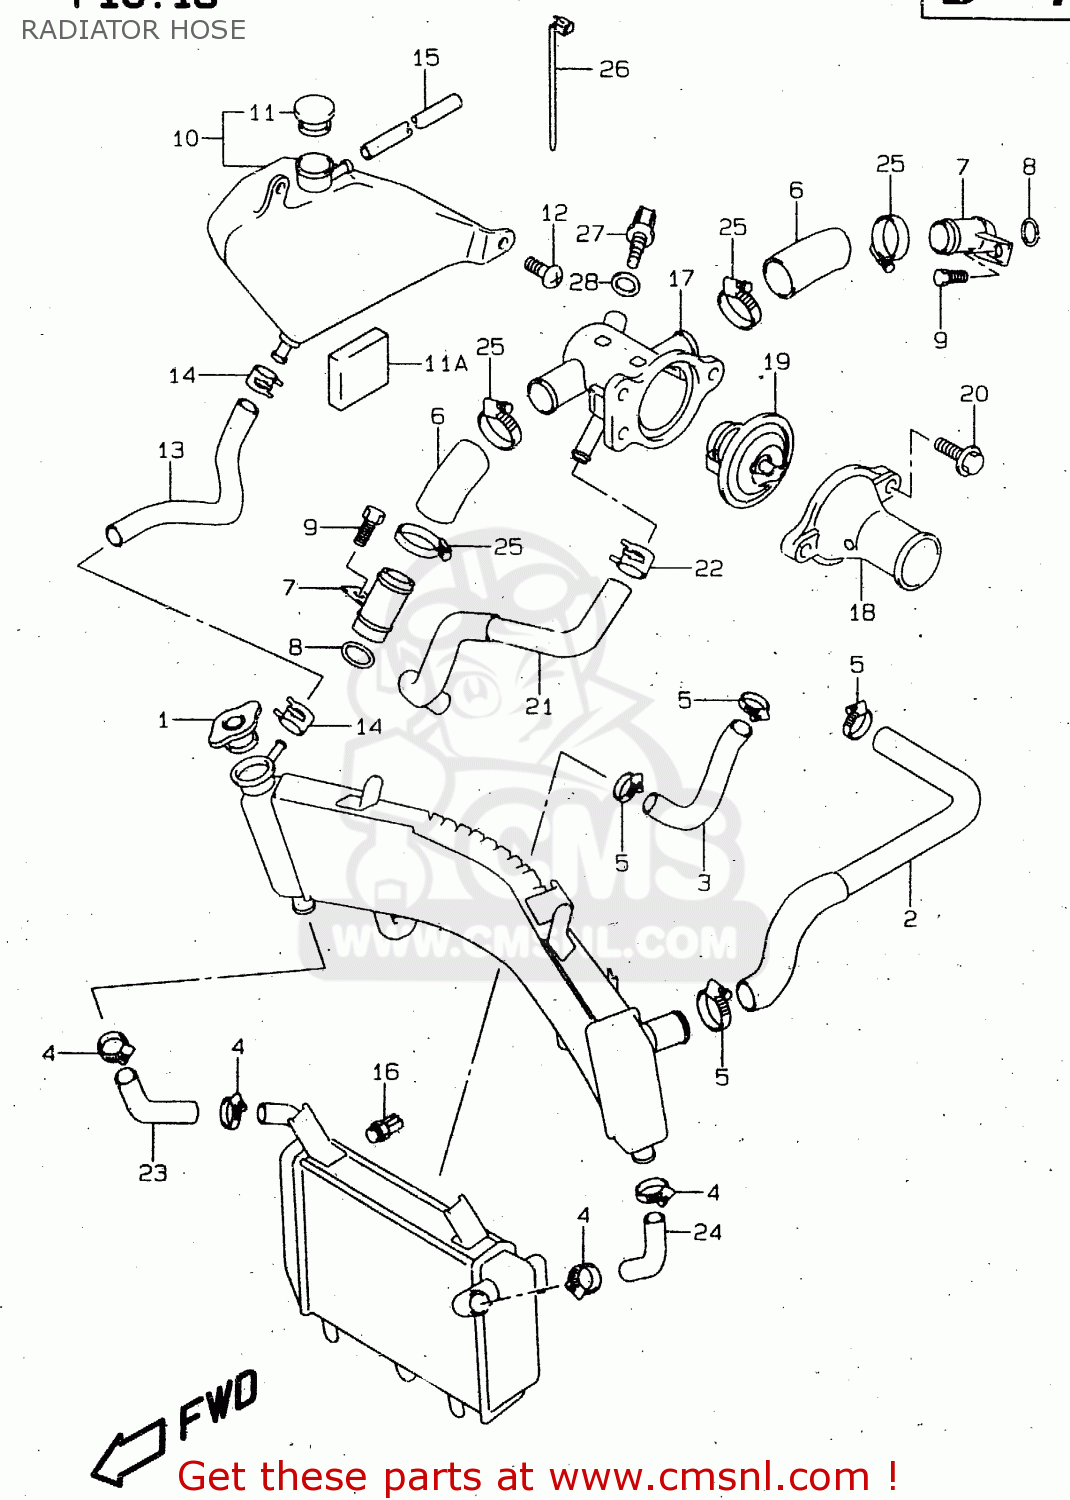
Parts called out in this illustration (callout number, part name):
1	CAP,RADIATOR
2	HOSE,RADIATOR INLET
3	HOSE,RADIATOR OUTLET
4	CLAMP
5	CLAMP
6	HOSE,CONNECTOR INLET
7	UNION,CONNECTOR HOSE
8	O RING(D:3.2,ID:17.8)
9	BOLT,STRANGER
10	TANK ASSY,RESERVOIR
11	CAP,RESERVOIR TANK
11A	CUSHION,HEADLAMP COVER
12	BOLT
13	HOSE,RESERVOIR TANK INLET
14	CLIP
15	HOSE,RESERVOIR TANK OVERFLOW
16	SWITCH,RADIATOR FAN
17	CONNECTOR,THERMOSTAT,INLET
18	CAP,THERMOSTAT CONNECT
19	THERMOSTAT,WATER 82 DEG
20	BOLT
21	HOSE,CONNECTOR TO WATER PUMP
22	CLAMP
23	HOSE,RADIATOR JOINT
24	HOSE,RADIATOR JOINT,L
25	CLAMP
26	CLAMP(L:125)
27	SENSOR,WATER TEMP
28	GASKET(12.2X21X0.8) (NAS)
